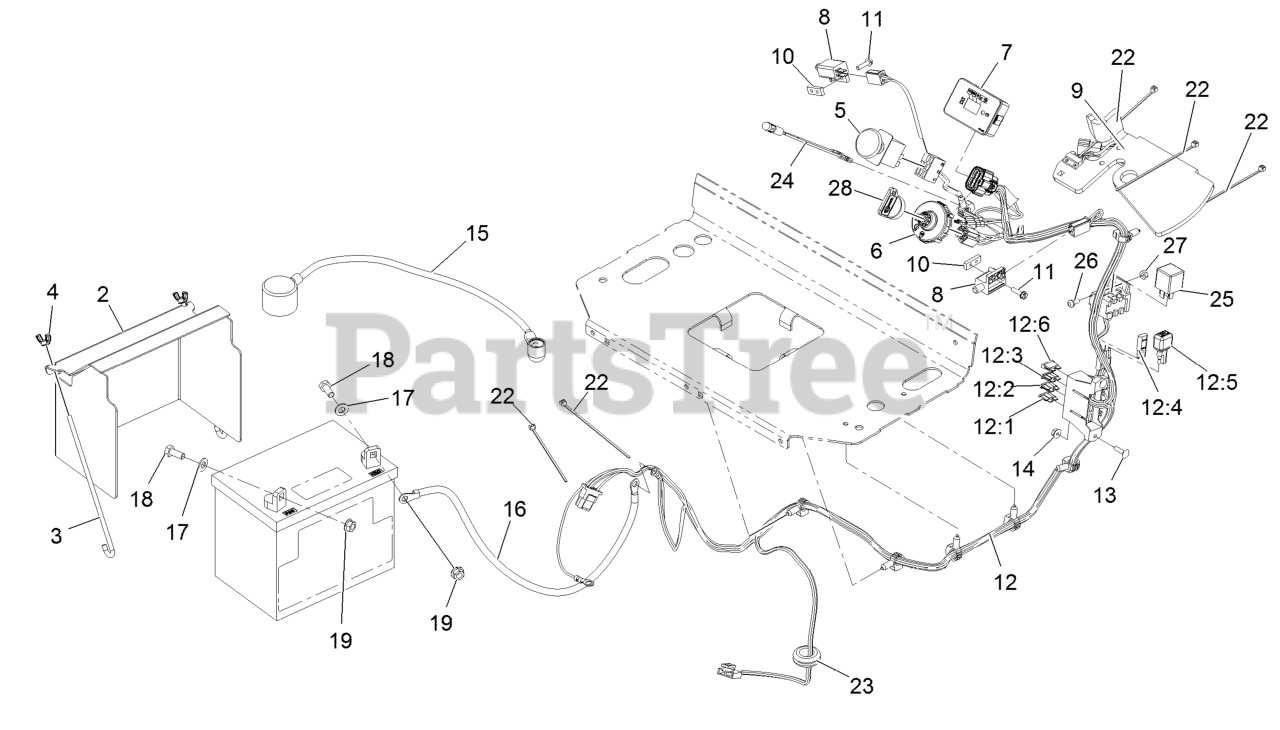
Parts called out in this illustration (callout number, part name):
2	COVER-BATTERY
3	BOLT-HOLDDOWN
4	WINGNUT
5	SWITCH-PTO, ON-ON
7	MODULE-HOUR METER
8	SWITCH-CLOSED, NORMALLY
9	HARNESS-SWITCH, REED
10	PLATE-TAPPED
11	SCREW-HWH
12	HARNESS-WIRE, EFI
12:1	FUSE-BLADE, 30 AMP
12:2	FUSE-BLADE, 25 AMP
12:3	FUSE-BLADE, 10 AMP
12:4	CAP-PLUG
12:6	FUSE-BLADE, 15 AMP
13	SCREW-CARR
15	CABLE-BATTERY, POSITIVE
16	CABLE-BATTERY, BLACK
17	WASHER-PLAIN
18	SCREW-HH
19	NUT-HHF, SMOOTH
22	TIE-CABLE
23	GROMMET
24	INDICATOR-LED, RED
26	SCREW-PPH
27	NUT-LOCK, NI
28	KEY-IGNITION
